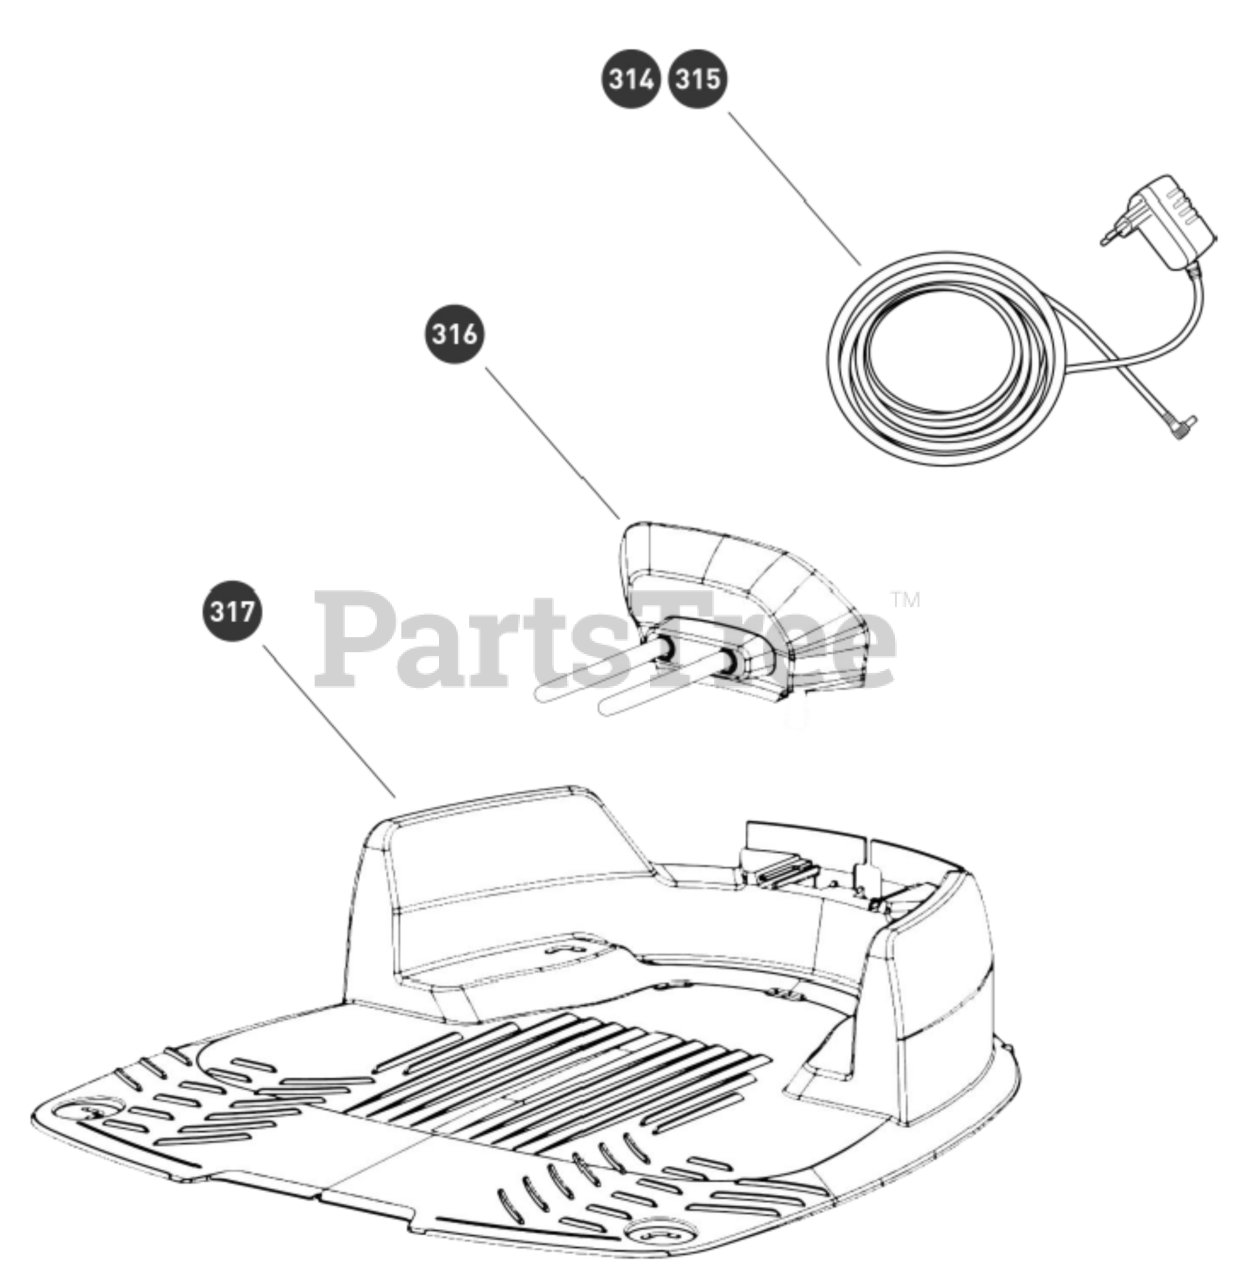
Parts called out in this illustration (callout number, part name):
314	10MM POWER SUPPLY WALL MT 17V
315	POWER SUPPLY W/18M CABLE
316	BASE STATION HEAD ASSEMBLY RX
317	BASE STATION RX
